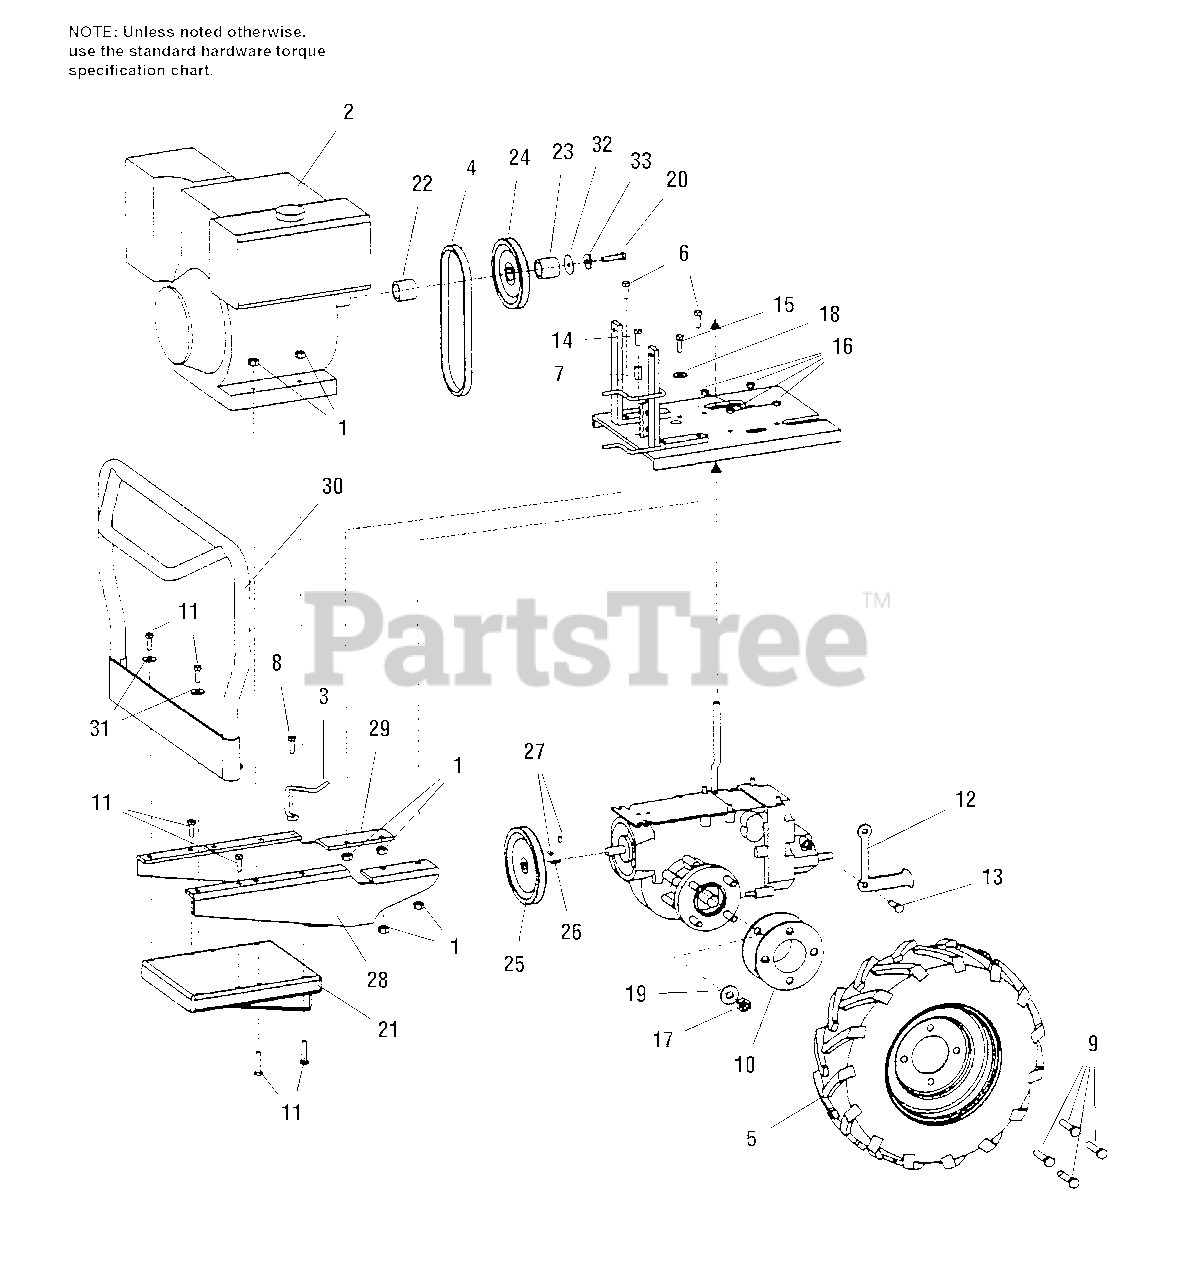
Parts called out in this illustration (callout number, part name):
1	NUT-Bi-Way Lock, 5/16-18
3	GUIDE-Belt, Forward
4	BELT-Forward
5	WHEEL/TIRE ASSEMBLY, Left Side
5	WHEEL/TIRE ASSEMBLY, Right Side
6	BOLT-Hex Hd, 5/16-18 x 1-1/4"
8	BOLT-Hex Flange Hd, 5/16-18 x 3/4", Grade 5
9	BOLT-Lug,1/2-20 x 3/4"
10	ADAPTER-Wheel
11	BOLT-HHCS, 5/16-18 x 3", Grade 5
12	ARM-Forward/Reverse Shift
13	BOLT-Hex Hd, 6mm x 14mm
14	BOLT-Hex Hd, 8mm x 16mm
15	BOLT-Hex Hd, 8mm x 22mm
16	NUT, 8mm x 1.25mm
17	NUT, 12mm x 1.25mm
18	WASHER-Wavy, 8mm
19	WASHER, 12mm
20	BOLT-Hex Hd, 7/16-20NF x 1", Grade 5
21	WEIGHT CASTING
22	SPACER-Engine Pulley, Short, Engine Side
23	SPACER-Engine Pulley, Long
24	PULLEY-Drive, Engine Forward
25	PULLEY-Drive, Transmission
26	KEY-Half Moon
28	BRACKET-Motor Mount, Left
29	BRACKET-Motor Mount, Right
30	BUMPER GUARD
31	WASHER-Flat, 5/16"
32	WASHER-Flat, 7/16"
33	WASHER-Spring Loc, 7/16"
